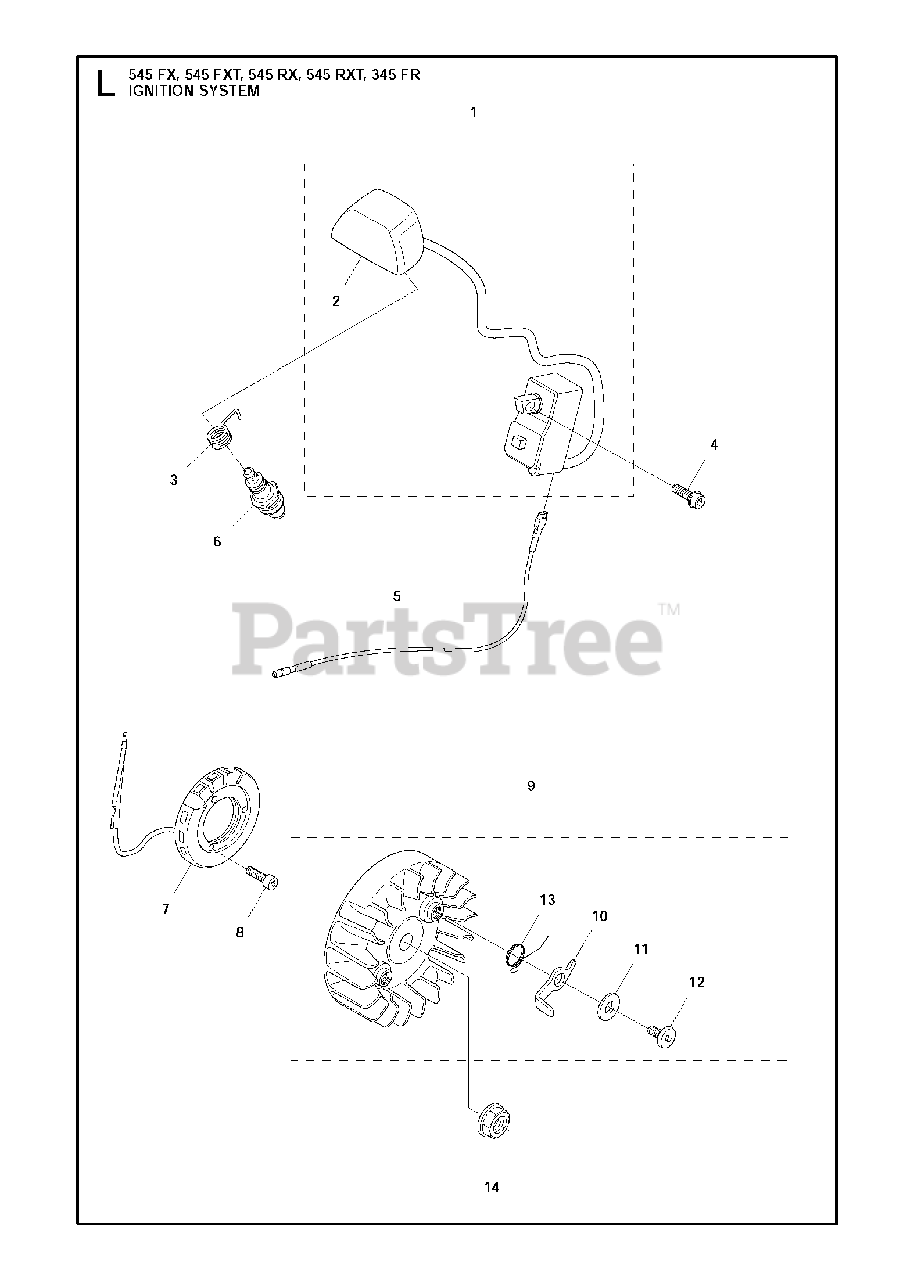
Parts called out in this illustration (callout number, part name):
1	IGNITION MODULE
2	SPARK PLUG CAP
3	Contact Spring
4	SCREW IHSCFM
5	SHORT CIRCUIT CABLE
6	CMR6H SPARK PLUG NGK
10	STARTER PAWL
11	WASHER
12	SCREW
13	SPRING
14	NUT W/ WASHER
